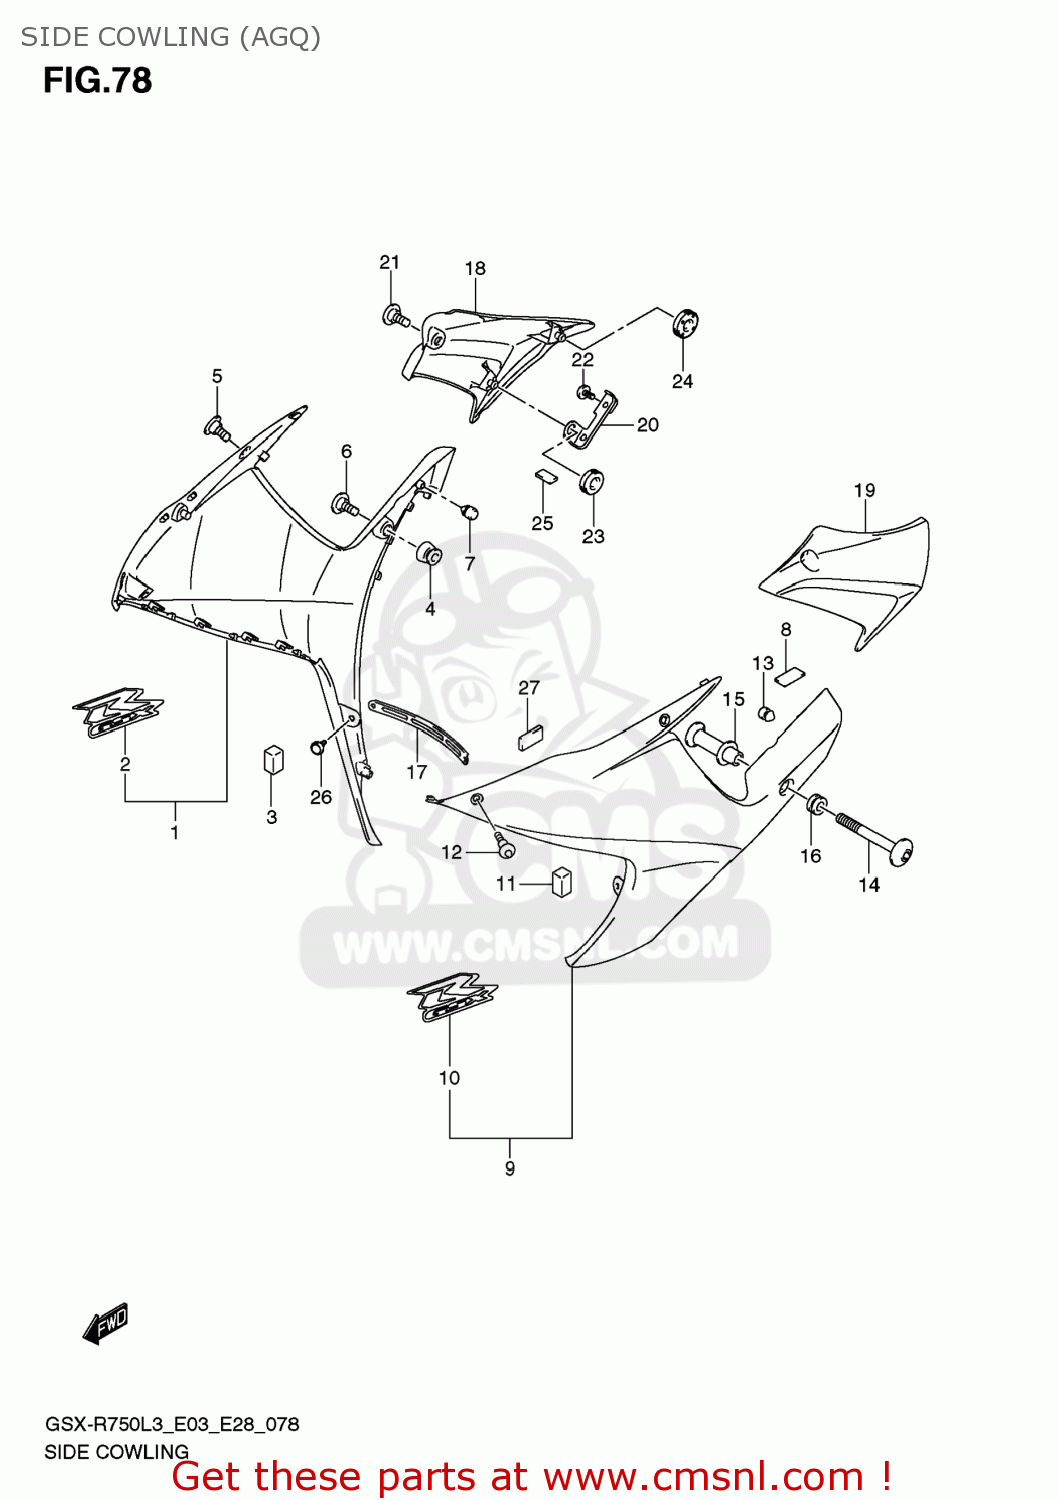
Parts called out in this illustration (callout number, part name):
1	COWLING,SIDE,R(BLUE)
2	EMBLEM,GSXR,R
3	CUSHION,SIDE COWL FR
4	CUSHION,UNDER COWLING,L
5	SCREW(5X13)
6	BOLT(6X20)
7	CUSHION
8	CUSHION,FUEL TANK NO.2
9	COWLING,SIDE,L(BLUE)
10	EMBLEM,GSXR,L
11	CUSHION,SIDE COWL FR
12	SCREW(5X13)
13	CUSHION
14	SCREW,SIDE COWL,L
15	SPACER,SIDE COWL,L
16	CUSHION
17	PLATE,UNDER COWL CTR
18	COVER,SIDE COWLING,R
19	COVER,SIDE COWLING,L
20	BRACKET,COVER SIDE,R
21	SCREW(5X13)
22	SCREW(6X12)
23	CUSHION
24	CUSHION
25	CUSHION
26	CLIP
27	PROTECTOR(30X80X1)
